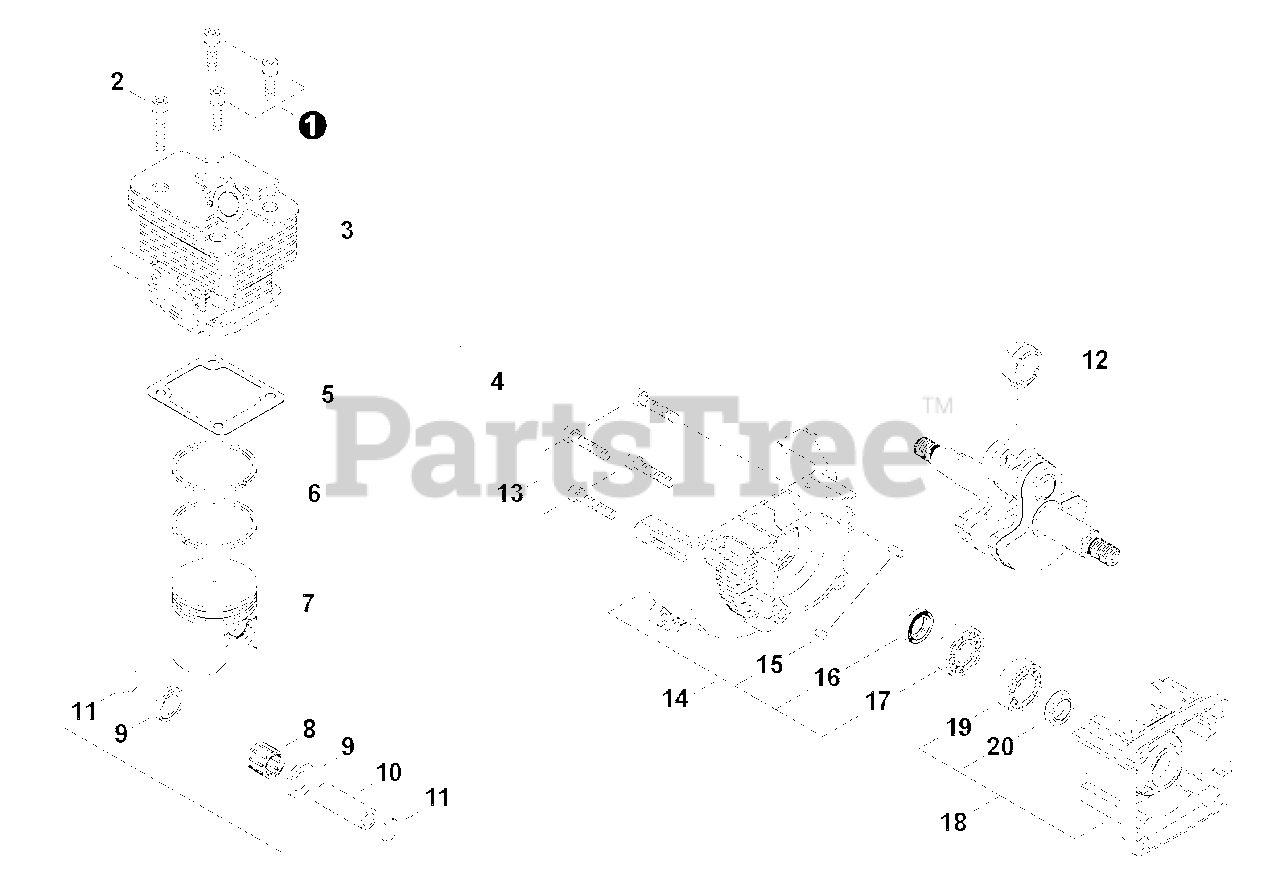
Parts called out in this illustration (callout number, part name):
1	Bolt M5x16
3	Cylinder
4	Piston Kit
5	Gasket, Cylinder
6	Ring, Piston
8	Bearing, Needle
9	Washer, Thrust 9
10	Pin, Piston
11	Ring, Snap
12	Crankshaft Assy
13	Bolt 5x25
14	Crankcase Assy, M
15	Pin, Locating 5x10
16	Seal, Oil 12
17	Bearing, Ball 6201 C3
18	Crankcase Assy, S
19	Bearing, Ball 6201 C3
20	Seal, Oil 12
